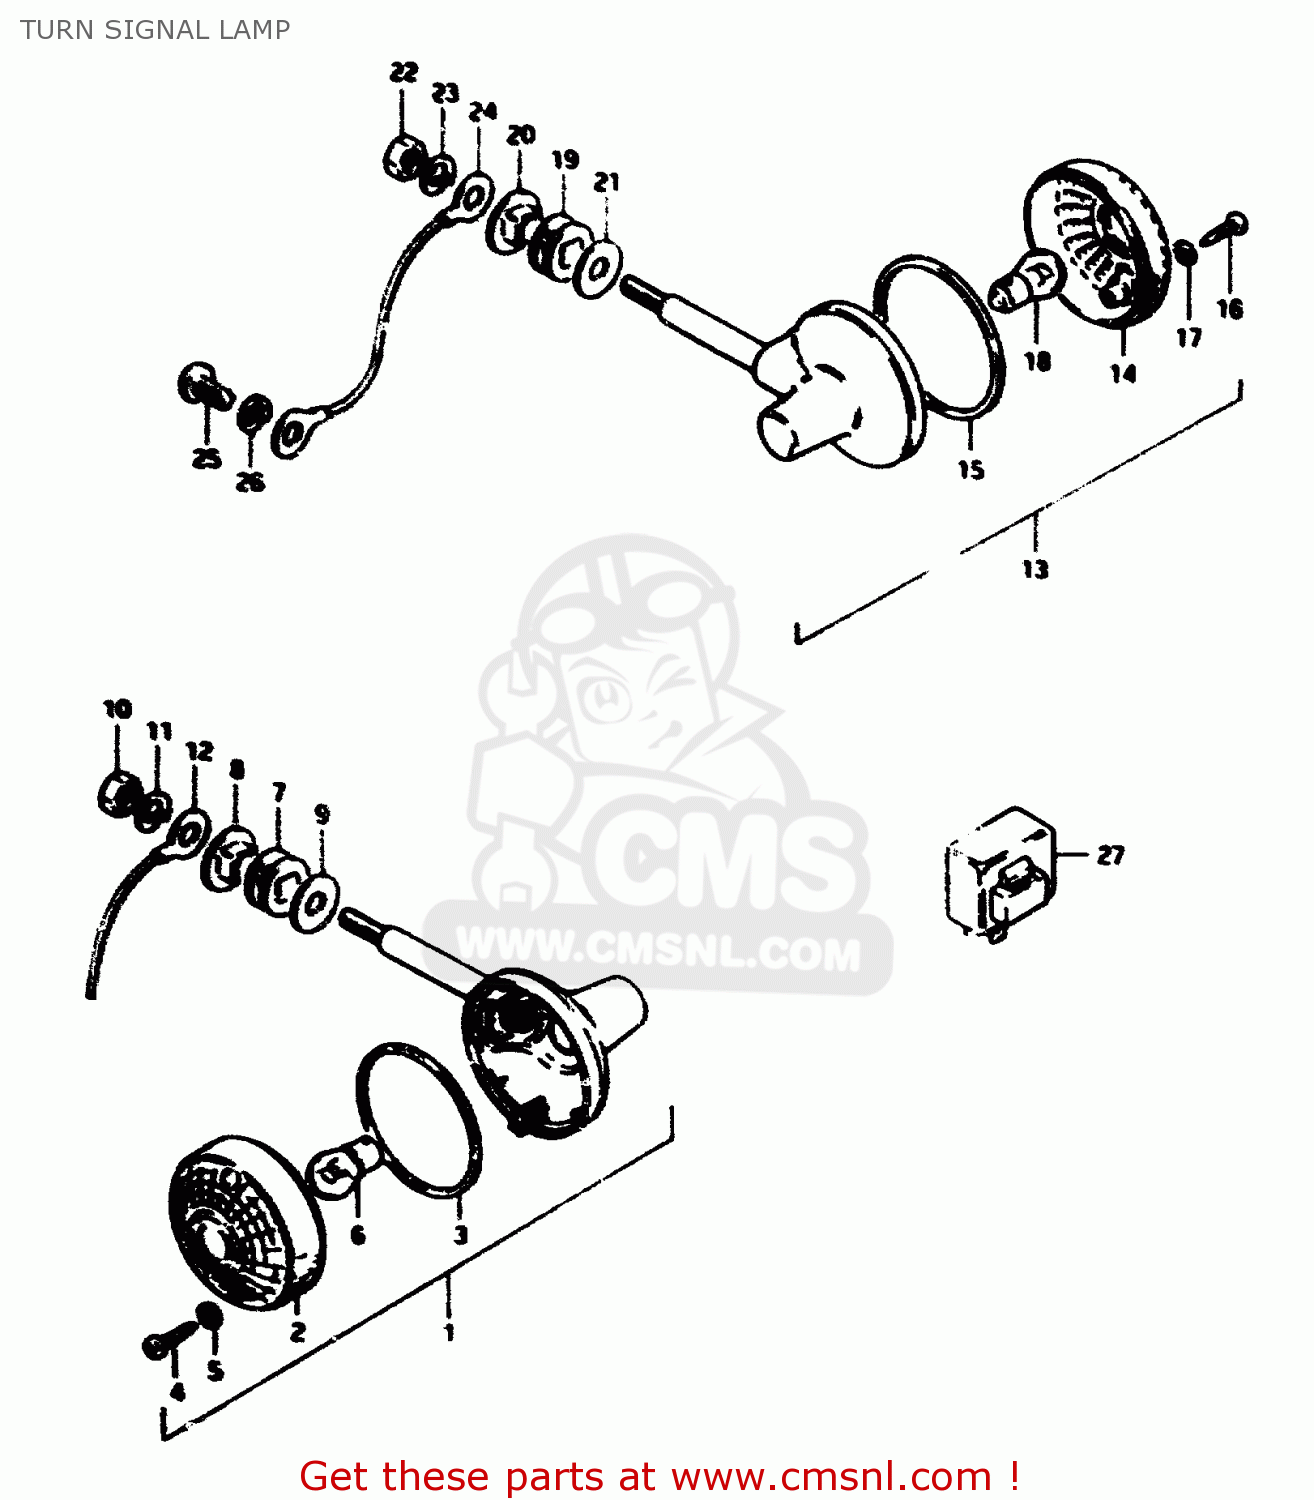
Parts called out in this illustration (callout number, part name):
1	LAMP, FRONT TURN SIGNAL
2	LENS
3	GASKET (NAS)
4	SCREW
5	GASKET (NAS)
6	BULB (6V,18W)
7	CUSHION
8	SPACER
9	WASHER (10.5X30X2.3)
10	NUT
11	LOCK WASHER
12	WIRE
13	LAMP, REAR TURN SIGNAL
14	LENS
15	GASKET (NAS)
16	SCREW
17	GASKET (NAS)
18	BULB (6V,18W)
19	CUSHION
20	SPACER
21	WASHER (10.5X30X2.3)
22	NUT
23	LOCK WASHER
24	LEAD WIRE
25	SCREW
26	LOCK WASHER
27	RELAY,TURN SIGNAL
